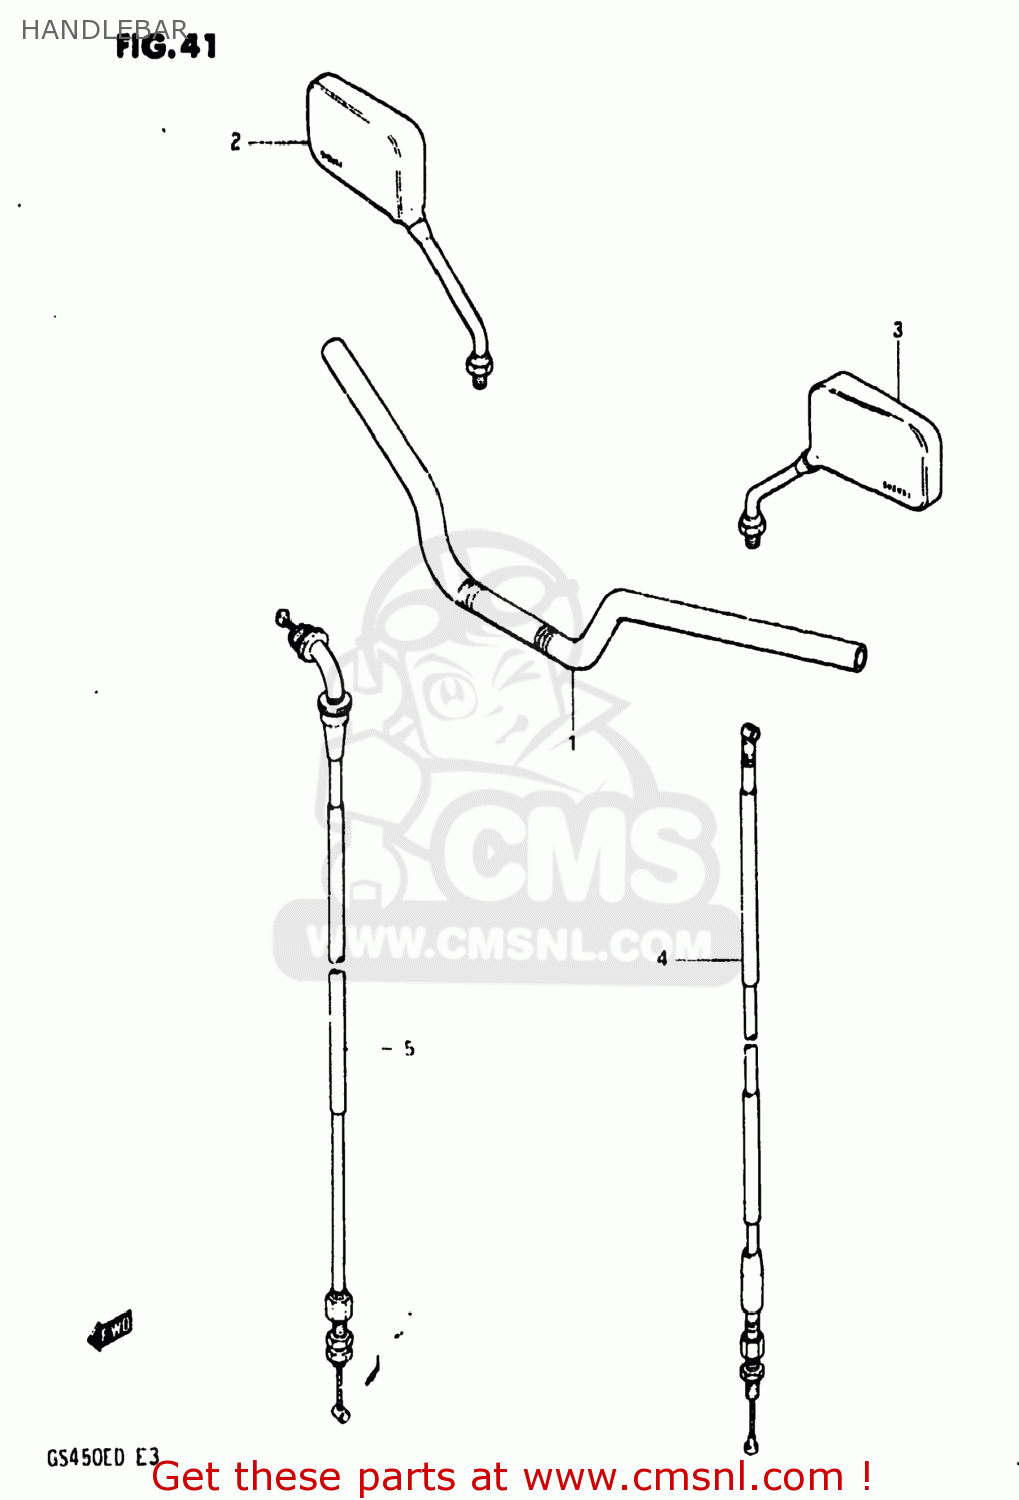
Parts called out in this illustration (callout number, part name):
1	HANDLEBAR
2	MIRROR ASSEMBLY,REAR VIEW
3	MIRROR ASSEMBLY,REAR VIEW
4	CABLE ASSY,CLUTCH
5	CABLE ASSEMBLY,THROTTLE
